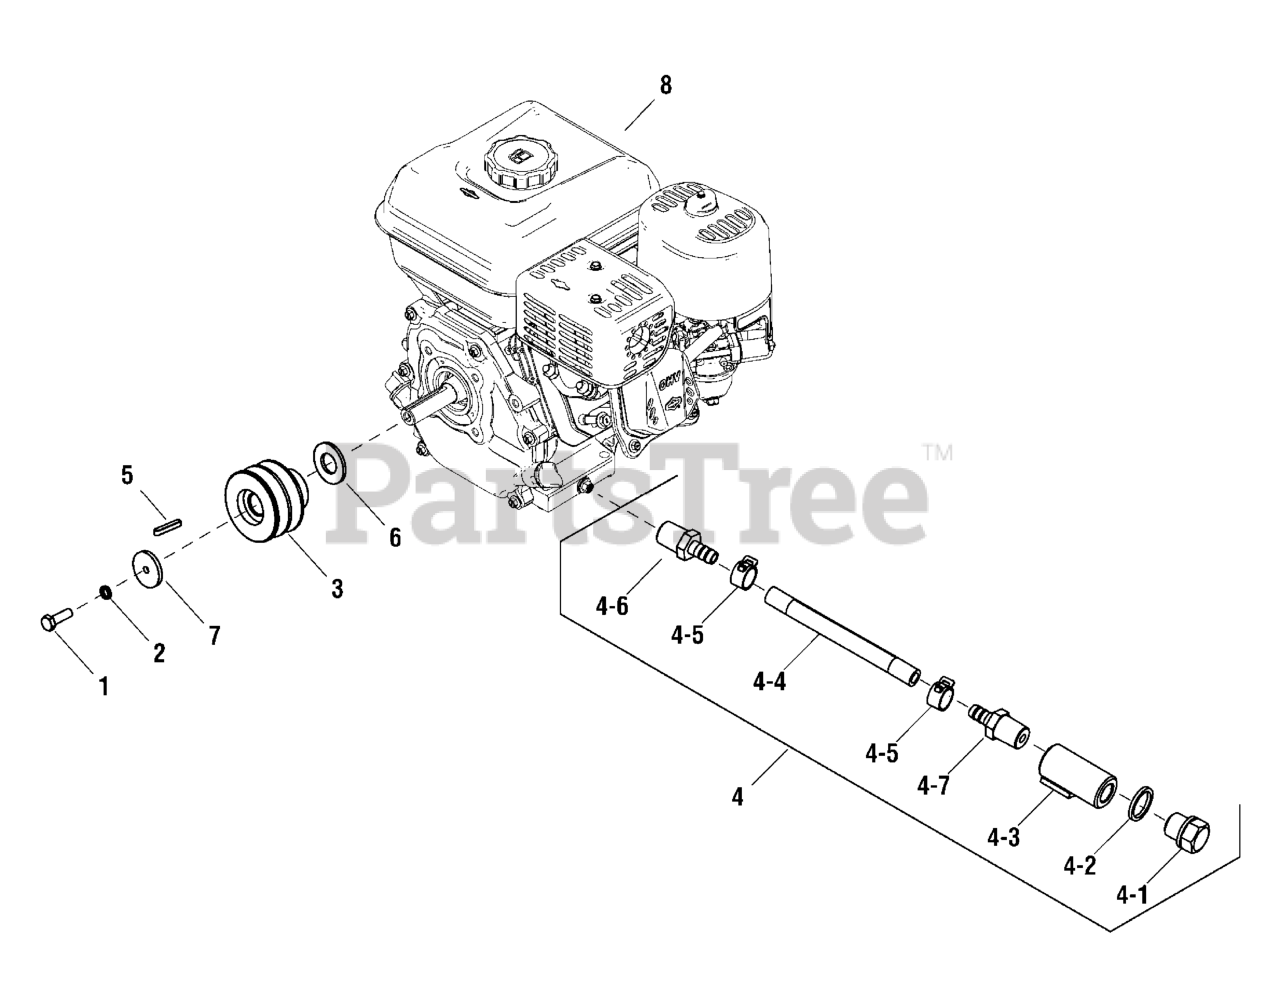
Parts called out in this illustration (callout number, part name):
1	BOLT, Hex, M8 x 25
2	WASHER, Spring, 8
3	PULLEY, Engine
4	EXHAUST OIL ASSEMBLY
4-1	PLUG, Hex Head, M14 x 1-1.5
4-2	GASKET, Sealing
4-3	NOZZLE
4-4	OIL HOSE
4-5	CLAMP, Spring
4-6	TAPER JOINT
4-7	TAPER JOINT
5	KEY, 5 x 32
6	WASHER, Flat
7	WASHER, Flat
8	ENGINE
